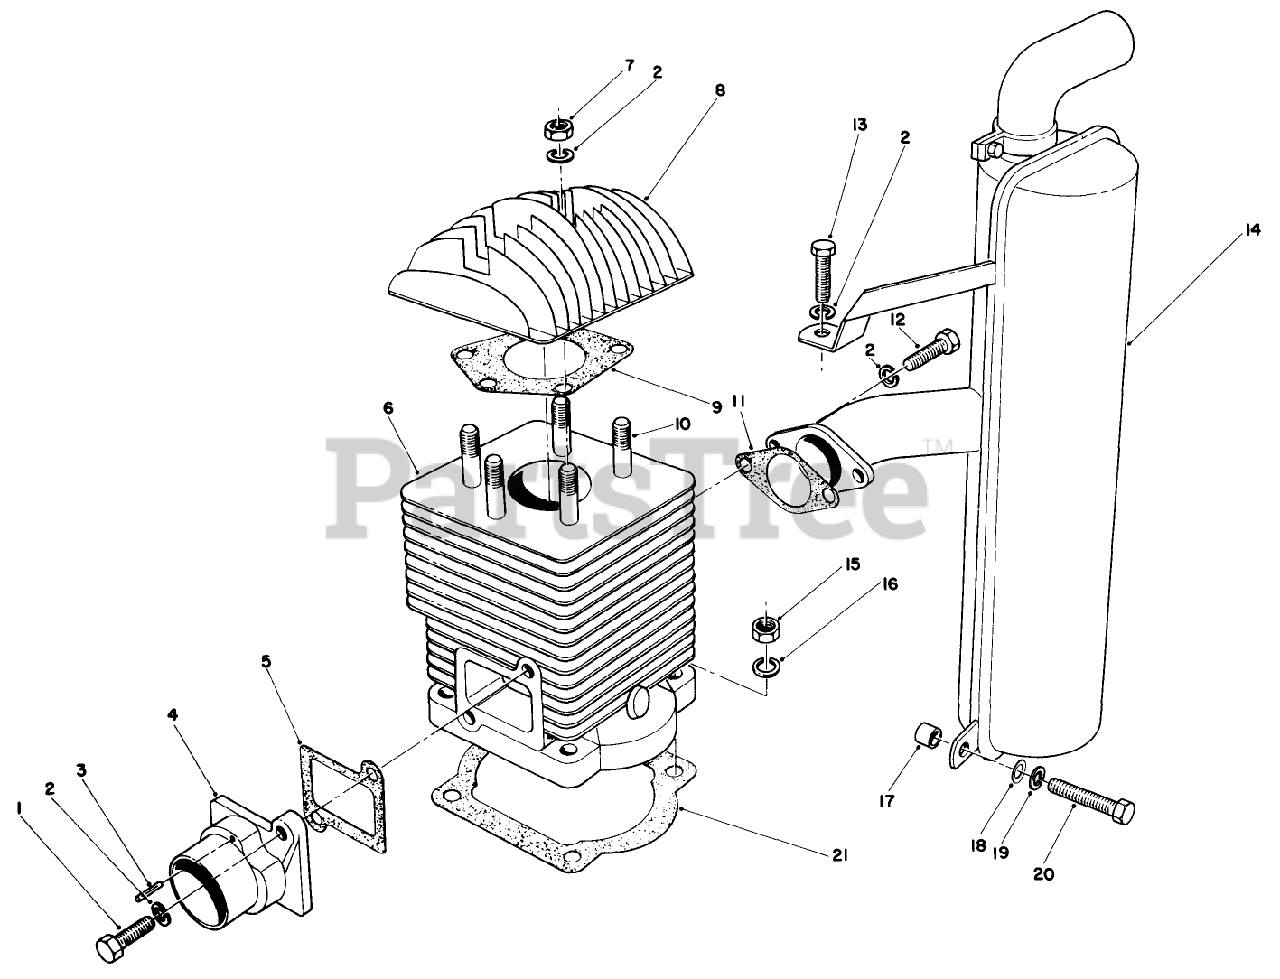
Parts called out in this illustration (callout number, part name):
1	NUT-LOCK, NI
2	RING-RETAINING
3	BRACKET-MOUNTING, GEARBOX
4	SCREW-HHFTF
5	COVER-DECK, RH
7	RH COVER ASM
8	WASHER-PLAIN
9	BRACKET-GEARBOX
10	SCREW-HH
11	GEARBOX-90 DEG
13	PULLEY
14	PULLEY
15	KEY-WOODRUFF
16	CENTER COVER ASM
18	SCREW-SET, HSH
19	V-BELT-DRIVE, DECK
21	SCREW-HH
22	NUT-LOCK, NI
23	FASTENER-1/4 TURN
24	DECAL-44 INCH
25	DECAL-WARNING, DEFLECTOR
26	DECAL-DANGER
